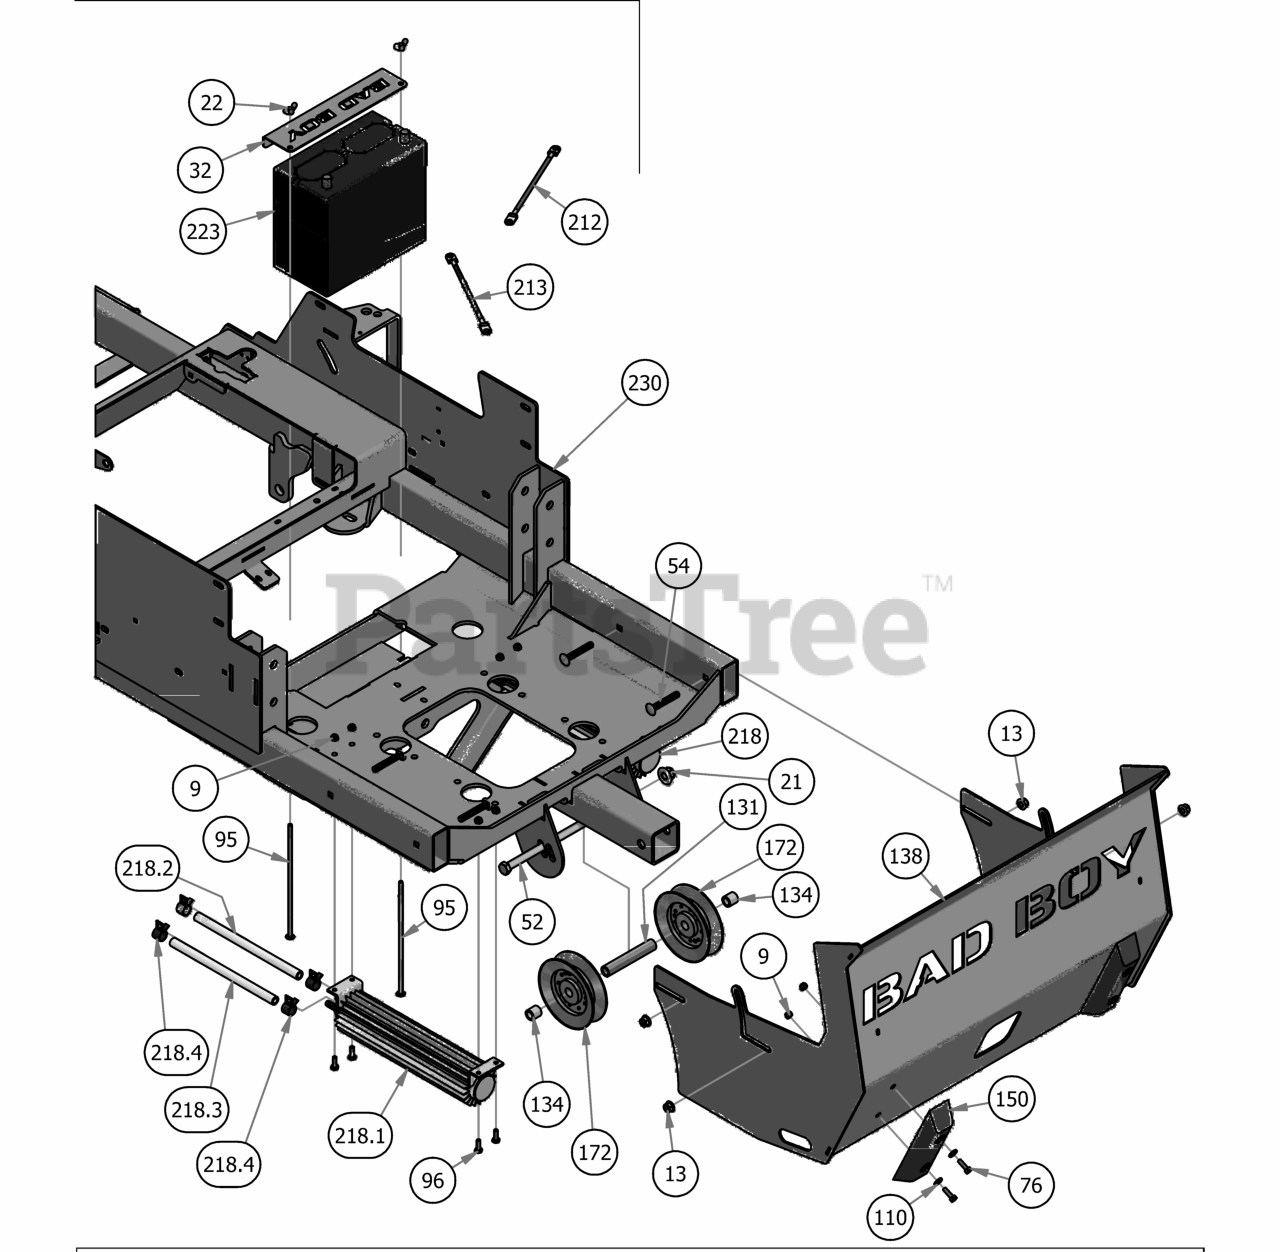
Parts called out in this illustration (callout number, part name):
9	1/4-20 Hex flang lock nut
13	3/8" Nylock Flange Nut
21	1/2-13 Nylon Flange Nut
22	1/4" Wing Nut
32	2019 Horizontal Battery Hold Down Cover
52	1/2" x 8 1/2 GR 5 Hex Bolt
54	3/8" x 2 1/2" Carriage Bolt
76	1/4-20 x 1-1/4 GR 5 Hex Bolt
95	1/4" x 1" Carriage Bolt
96	1/4" x 3/4" Hex Bolt
110	1/4" Flat Washer
131	2019 Rear Vertical Pulley Spacer
134	Spacer 3/4 OD x 1/2 ID x 3\4 Length
138	2019 Horizontal Suspension Rear Cover
150	8" Rubber Bumper
172	2019 Outlaw Horizontal Rear V Pulley
212	Red Battery Cable - Diesel
213	Black Battery Cable - Diesel
218	Renegade Oil Cooler Assembly
218.1	2019 12" Oil Cooler With Fittings
218.2	3/8" Clear Hose
218.3	3/8" Clear Hose
218.4	3/8" Hose Clamp
223	Battery - Diesel/Renegade Models PF-516
230	2019 Horizontal Diesel Frame
